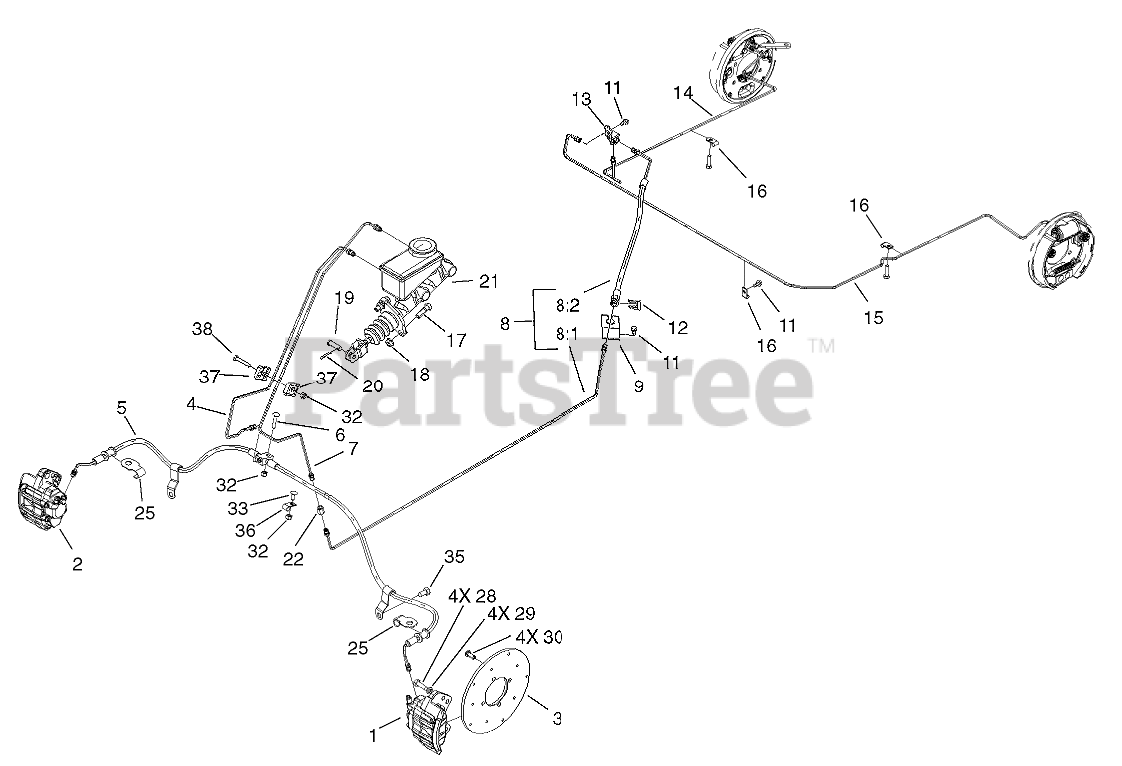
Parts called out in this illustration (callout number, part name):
1	CALIPER-LH
2	CALIPER-RH
4	TUBE-BRAKE, FRONT
5	BRAKE FRONT HOSE ASM
6	SCREW-CARR
7	TUBE-BRAKE, REAR
8	Complete Rear Brake Hose ASM
8:1	TUBE-BRAKE, REAR
8:2	HOSE-BRAKE, REAR
9	BRACKET-HOSE, BRAKE
11	SCREW
14	TUBE-BRAKE, REAR (RH)
15	TUBE-BRAKE REAR, LH
16	CLIP-CLOSED, INSULATED
17	SCREW-HH
18	NUT-HHF, WHIZ
19	PIN-CLEVIS
20	PIN-COTTER
21	MASTER CYLINDER ASM
22	UNION
25	BRACKET-HOSE
28	SCREW-HH
29	WASHER-LOCK
30	SCREW-HSBH
32	NUT-LOCK, NI
33	SCREW-CARR
35	SCREW-HWHTF
36	CLAMP-R
37	CLAMP-TUBE
38	SCREW-HH
